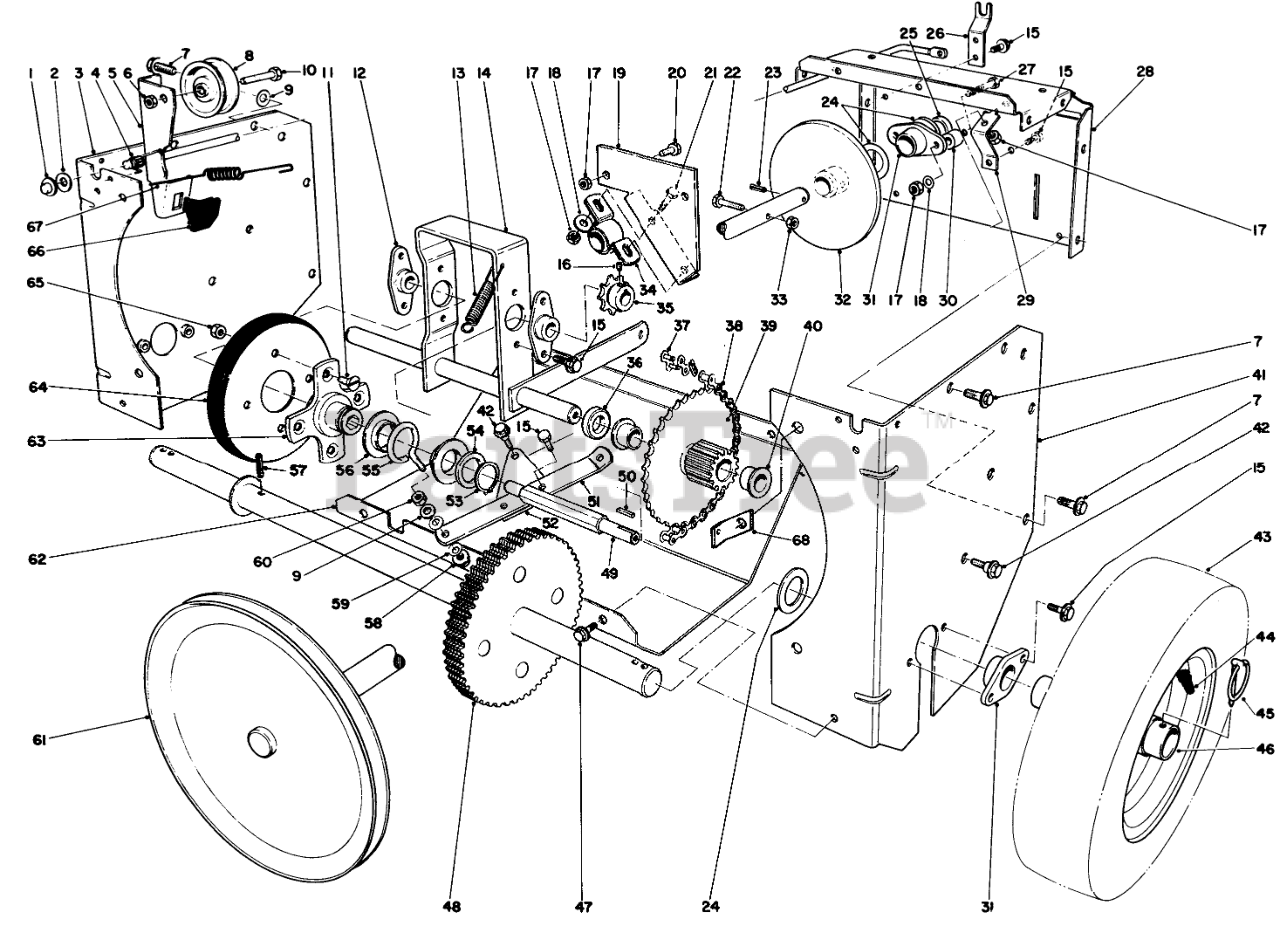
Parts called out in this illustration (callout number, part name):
1	PUSH NUT
2	WASHER-FLAT
3	RH TRACT SIDE PLT R
4	TORSION CLUTCH SPRING
5	Clutch Rod (Incl. Ref. #66)
6	NUT-LOCK, NI
7	SCREW-HWHTF
8	PULLEY-IDLER
9	WASHER-FLAT
10	SCREW-HH
11	5/16-18X5/8 FLT HD MS
12	BEARING-WHEEL, FRICTION
13	TENSION SPRING
14	PIVOT SHAFT WA B
15	SCREW-HWHTF
16	SCREW-HSH
17	NUT-LOCK, NI
18	WASHER-PLAIN
19	SHAFT SUPT BRKT B
20	SCREW-HH
21	SCREW-HH
22	SCREW-HH
23	PIN-ROLL, SLOTTED
24	WASHER
25	DRIVE SHAFT SPACER
26	CLUTCH ROD SUPPORT
27	SCREW-HH
28	CENTER FRAME R
29	PIVOT BRACKET
30	BRG STANDOFF
31	AXLE BEARING
32	FRICTION PLT WA
33	NUT-LOCK, CONE
34	PILLOW BLOCK BRG
35	SPROCKET
36	COSHAFT SPACER
37	LINK-CONNECTING
38	ROLLER-CHAIN
39	Gear & Bushing (Incl. Ref. #40)
40	BUSHING
41	LH TRACT SIDE PLT R
42	SHOULDER SCREW
44	TUBE-INNER
45	PIN-LYNCH
46	WHEEL
47	SCREW-HWH
48	AXLE & GEAR WA
49	FRICTION WHL SHAFT
51	SHIFT LINKAGE
52	PIVOT PLATE
53	RING-RETAINING
54	WASHER-THRUST
55	SLIDER RING COLLAR
56	SLIDER RING
57	PIN-ROLL, SLOTTED
58	NUT-LOCK, FLANGE
59	WASHER-SPRING
60	NUT-LOCK
61	PULLEY/SHFT WA
62	LOWER SHIELD R
63	TRACTION DISC HUB
64	FRICTION WHEEL
65	NUT-LOCK, NI
66	PAD-BRAKE
67	SPRING
68	SPRING BRACKET
